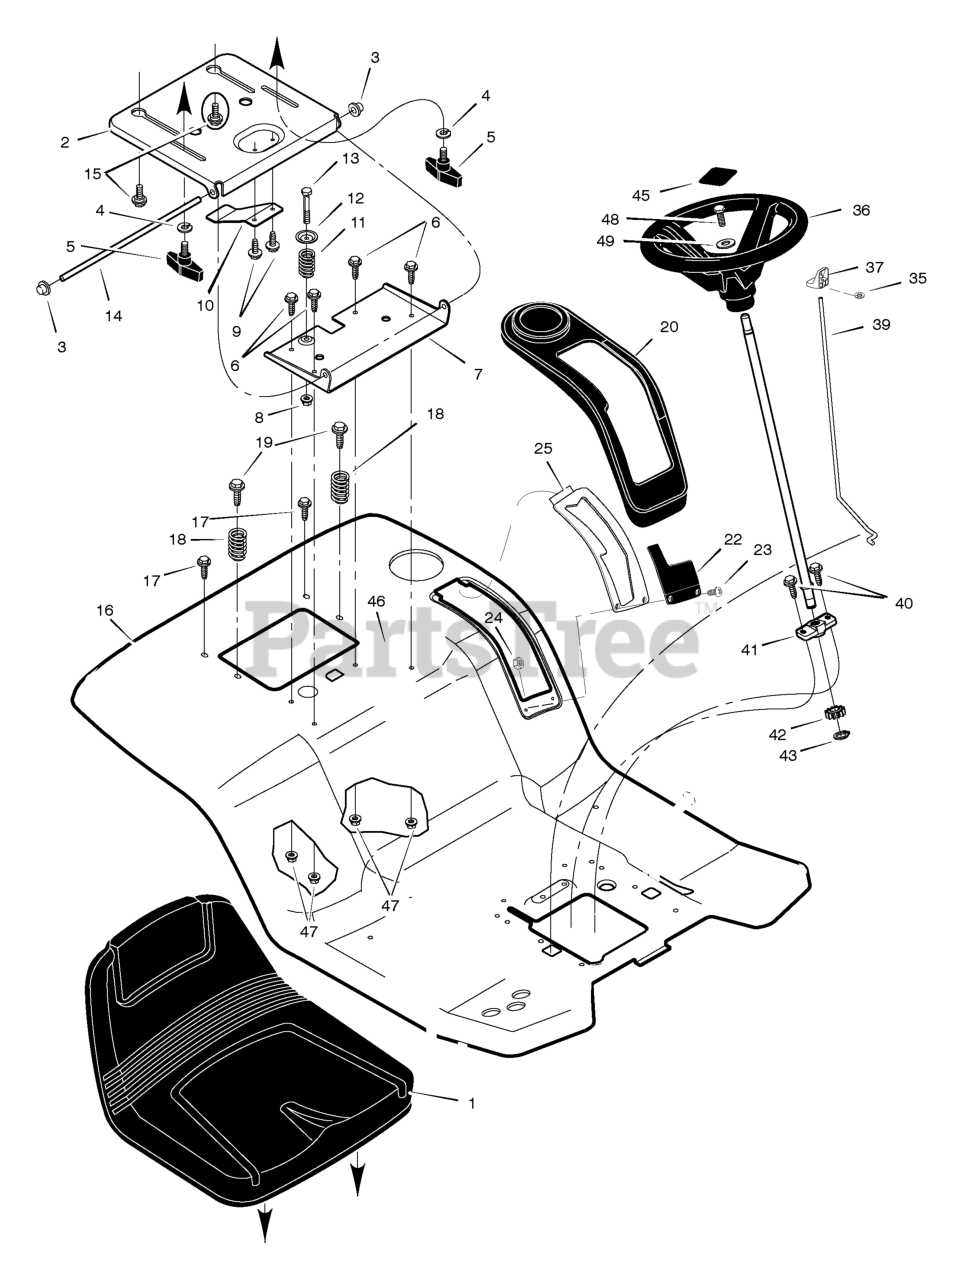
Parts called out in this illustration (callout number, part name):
2	Support, Seat
3	Push-On Cap
4	Washer
5	Bolt, Wing
6	Bolt
7	Bracket, Pivot
10	Spring, Leaf
11	Spring
12	Washer, Cup
14	Rod, Pivot
15	Bolt, Shoulder
16	Deck, Seat
20	Cover, Detent with Cup Holder
22	Cover, Detent
25	Plate, Detent
35	Nut, Push
36	Wheel, Steering
37	Knob, Parking Brake
39	Rod, Parking Brake
41	Bearing, Lower
42	Gear, Pinion
44	Shaft, Steering
45	Insert, Steering Wheel
47	Nut
48	Screw, Hex
49	Washer
